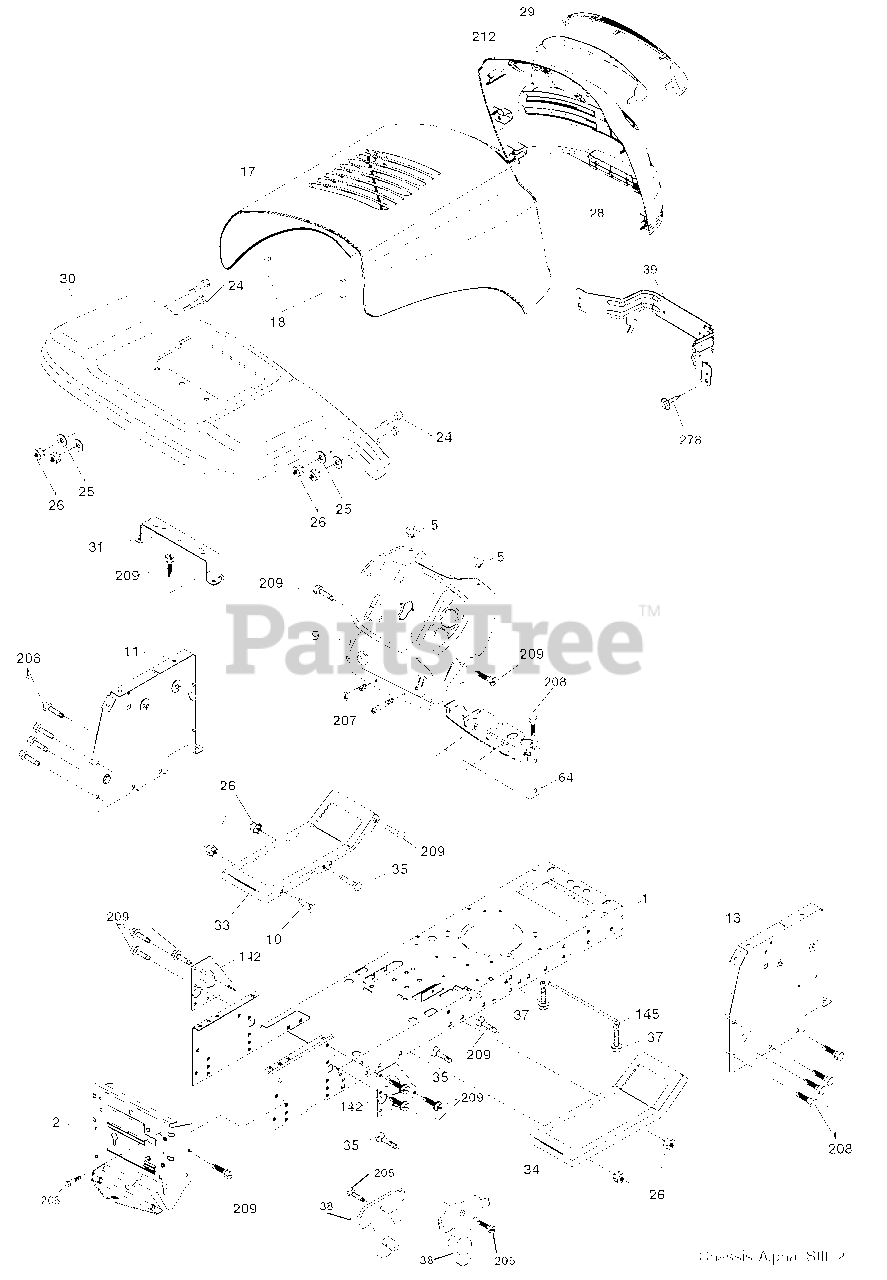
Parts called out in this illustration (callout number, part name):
1	Chassis
2	Drawbar, Stretch
5	Bumper, Hood/Dash
9	Dash
10	Bolt, Carriage 3/8-16 x 1
11	Panel Dash LH
13	Panel Slkscr Dash RH
17	Hood
18	Bumper Hood
24	Bolt Fin Hex 3/8-16 unc x 1 Gr. 5
25	Washer 13/32 x 13/16 x 12 Ga.
26	Nut Lock Hex w/Ins 3/8-16 unc
28	Grille/Lens Asm
29	Lens Grille Basic Bar
30	Fender
31	Bracket Fender Repl 109873X
33	Footrest Pnt LH
34	Footrest Pnt RH
35	Bolt Rdhd Sht Sqnk 3/8-16 x 3/4
37	Screw Thdrol 5/16-18 x 1/2 TYT
38	Bracket Asm. Pivot Mower
39	Bracket Pivot
64	Dash Lower
142	Plate Reinforcement
145	Rod Pivot Chassis/Hood
205	Screw Thdrol 3/8-16 x 1/2
206	Bolt Shoulder 5/16-18
207	Screw Thdrol 5/16-18 x 1/2
208	Screw Thdrol 3/8-16 x 1/2
209	Screw Hex Wsh Thdrol 3/8-16
212	Insert Lens Reflect
278	Screw 10 x 3/4 Single Lead-Hex
278	Plug Button Blk 359 Dia Choke
278	Plug Dome Plastic
